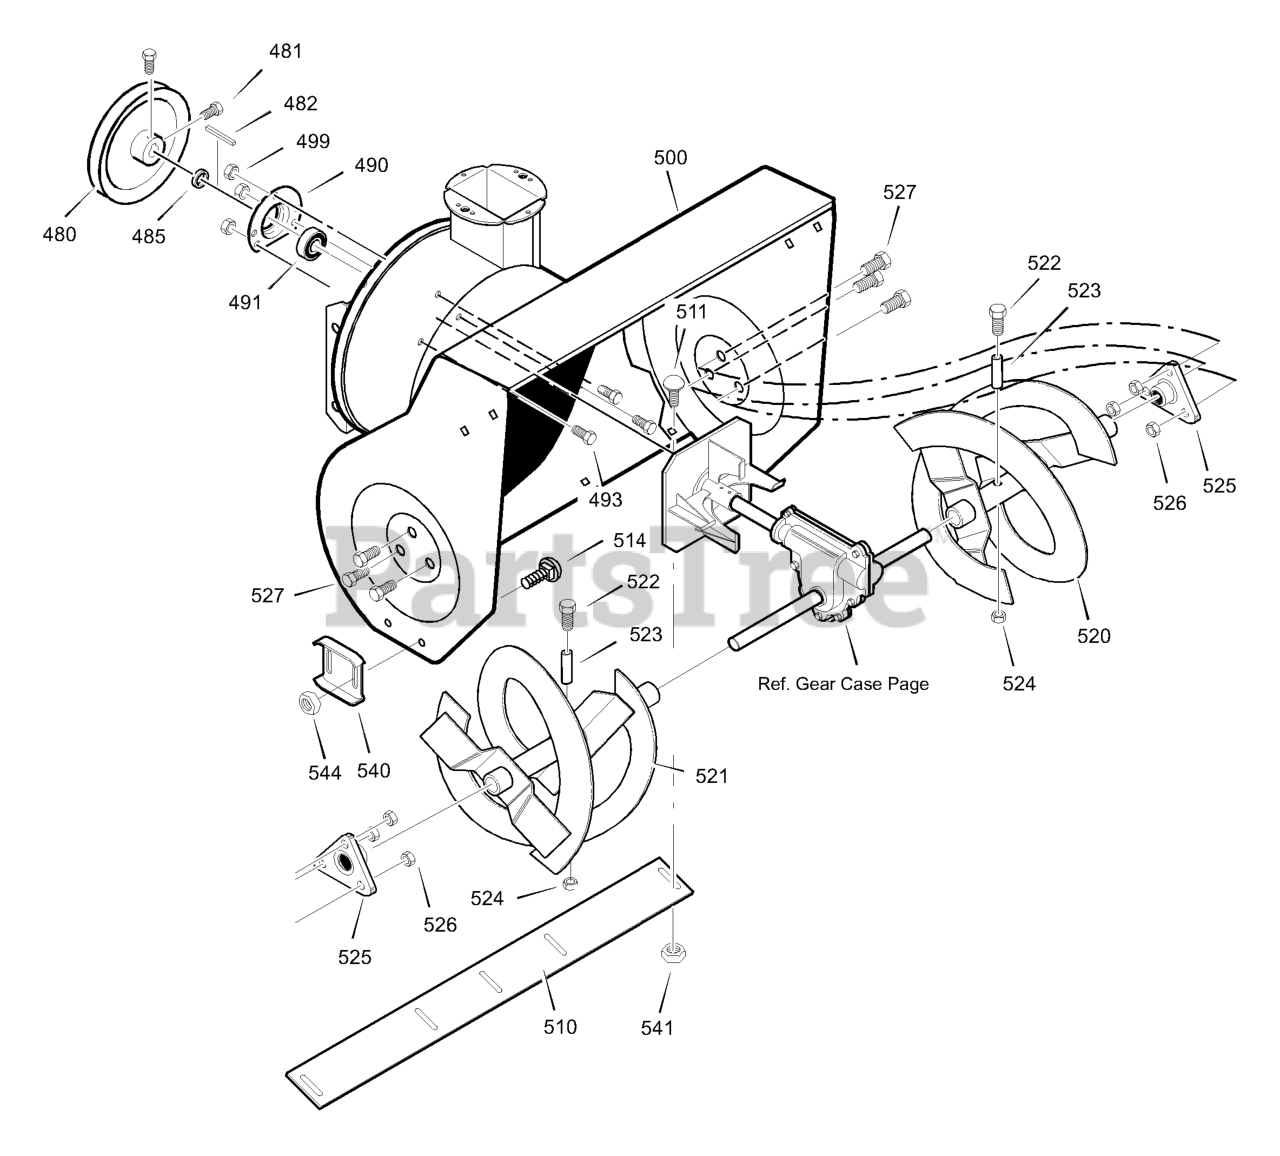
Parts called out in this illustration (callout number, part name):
480	PULLEY, 4L 6.12X .67
481	SCREW, 5/16-18 x 0.63
482	KEY, SQUARE 3/16 X 3/4
485	SPACER, FRICTION PULLEY
490	RETAINER, BALL BRNG
491	BEARING, BALL
493	BOLT, HEX 5/16-18X .50
499	NUT, 5/16-18 HEXWDFLLK
500	HOUSING, ASSY
509	FASTENER, RATCHET
510	BLADE, SCRAPER 24"
511	BOLT, 1/4-20X.75
514	NUT, 1/4-20
520	AUGER, ASSY, LH
521	AUGER, ASSY, RH
522	SCREW, 1/4-20X1.75
523	SPACER, SLEEVE
524	NUT, 1/4-20
525	BEARING,FLANGE
526	NUT, 5/16-18
527	SCREW, 5/16-18 x 0.75
540	SKID, HEIGHT ADJUST
541	BOLT, 5/16-18 X .75
544	NUT, 5/16-18
